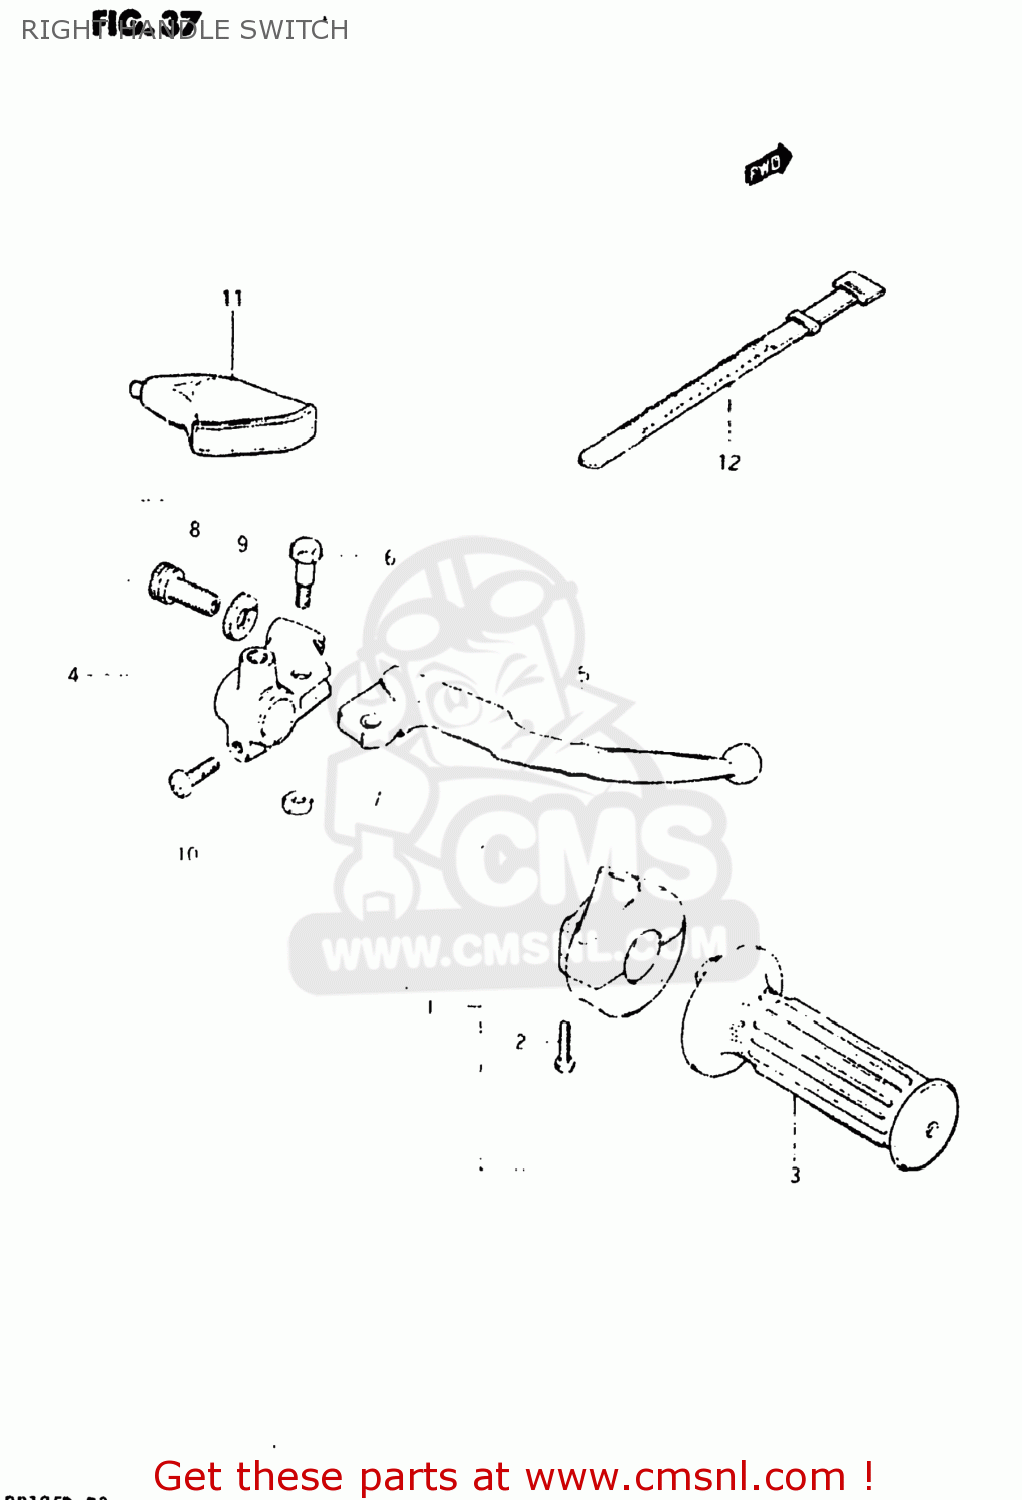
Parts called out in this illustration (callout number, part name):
1	CASE ASSY,THROTTLE
2	SCREW 5X20
3	GRIP,THROTTLE
4	LEVER ASSEMBLY,BRAKE
5	LEVER,BRAKE
6	BOLT,LEVER
7	NUT 6MM
8	ADJUSTER,CABLE
9	NUT,CABLE ADJUSTER
10	SCREW
11	COVER,CLUTCH LEVER
12	CLAMP(L:120)
